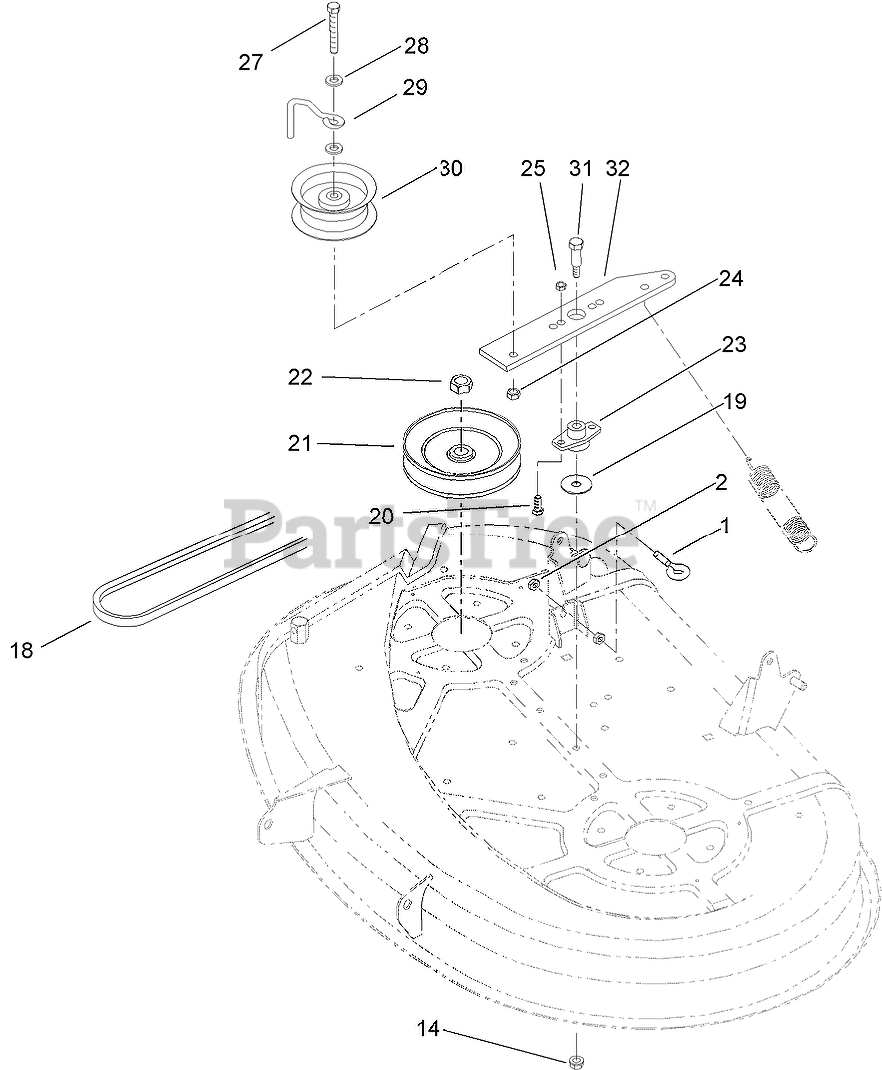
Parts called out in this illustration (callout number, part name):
1	EYEBOLT
2	NUT-JAM
14	NUT-LOCK, NI
18	BELT-V
19	WASHER-FLAT
20	SCREW-HH
21	PULLEY
22	NUT-HEX
23	BUSHING-ARM, IDLER
24	NUT-LOCK, NI
25	NUT-LOCK, NI
27	SCREW-HH
28	WASHER-FLAT
29	GUIDE-IDLER, BELT
30	PULLEY-IDLER, FLAT
31	SCREW-SHOULDER, HH
32	ARM-IDLER
